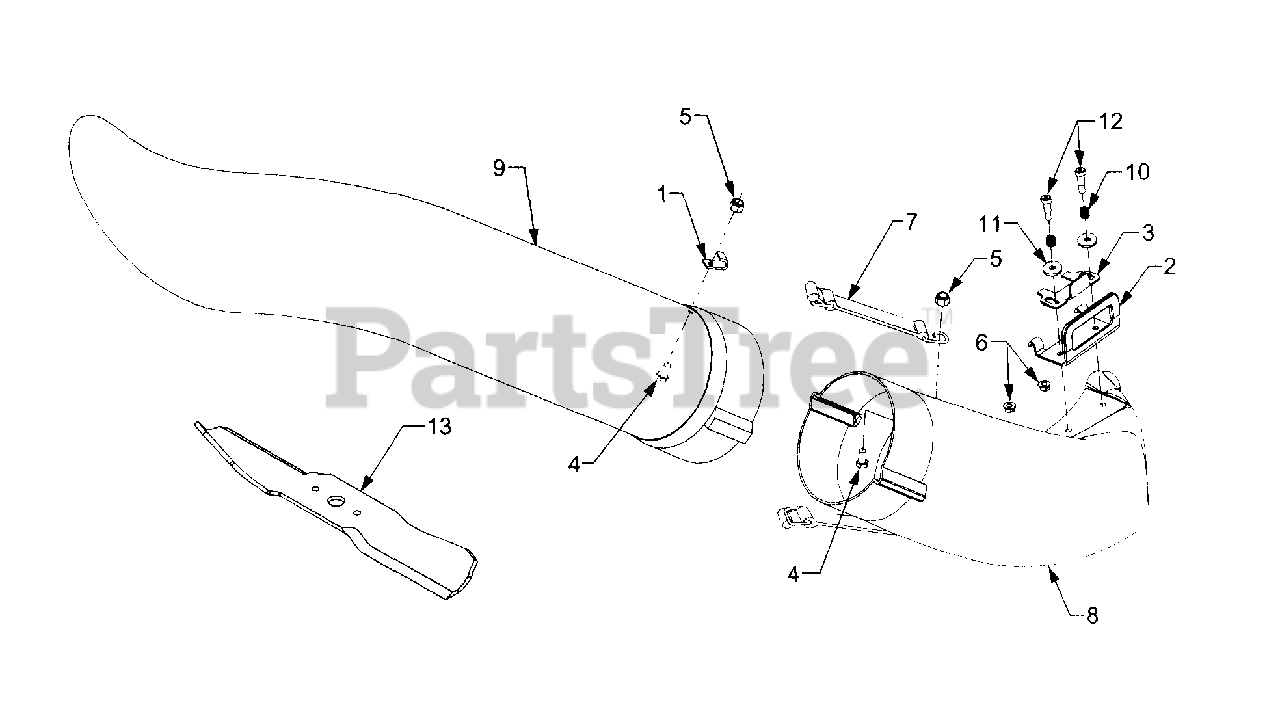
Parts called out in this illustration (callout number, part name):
1	Bracket, Retainer Hook
2	Bracket, Chute
3	Latch, Chute
4	Screw, Hex Cap, 1/4-20 x .62 GR5
5	Nut, Hex Insert Lock, 1/4-20
6	Nut, Hex Flange Lock, 5/16-18
7	Strap Assembly, Retainer
8	Chute, Discharge
9	Tube, Chute
10	Spring, Compression, .5 x .5 Lg.
11	Washer, Flat, 3/8 x 1.25
12	Screw, Shoulder 3/8 x .625: 5/16-18
13	Blade, High Lift
